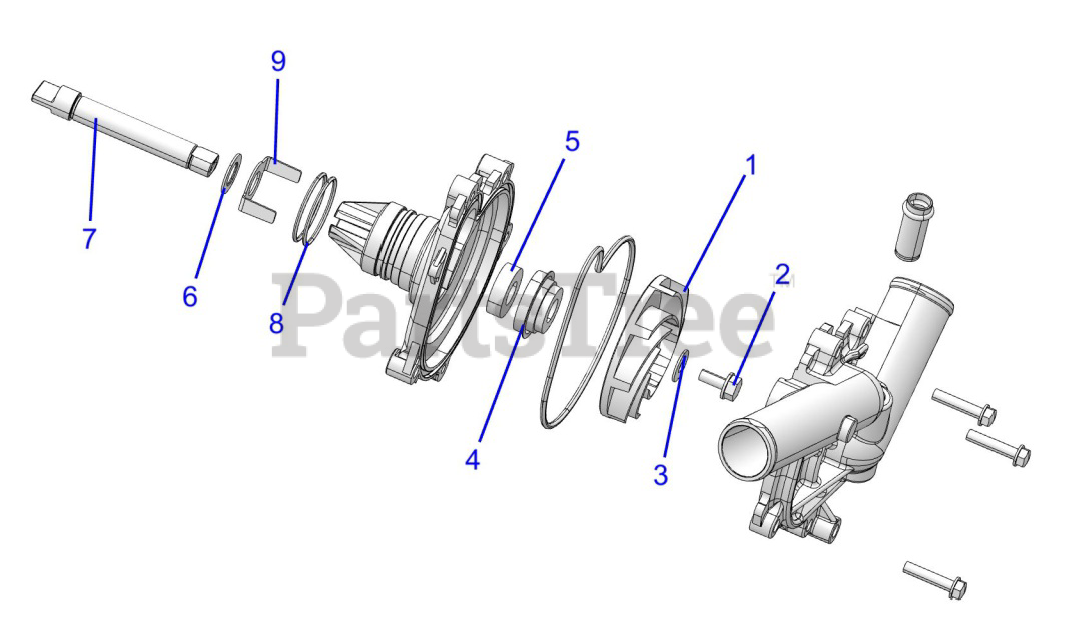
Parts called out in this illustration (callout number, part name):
1	ASM-WATER PUMP
1	IMPELLER, WATERPUMP
2	SCREW
3	WASHER, IMPELLER
4	SEAL, WATERPUMP SHAFT, MECHANICAL
5	SEAL, WATERPUMP SHAFT, OIL
6	WASHER, WATERPUMP, RETAINER
7	SHAFT, WATERPUMP,
8	O-RING
9	WASHER, WATERPUMP,RETAINER
